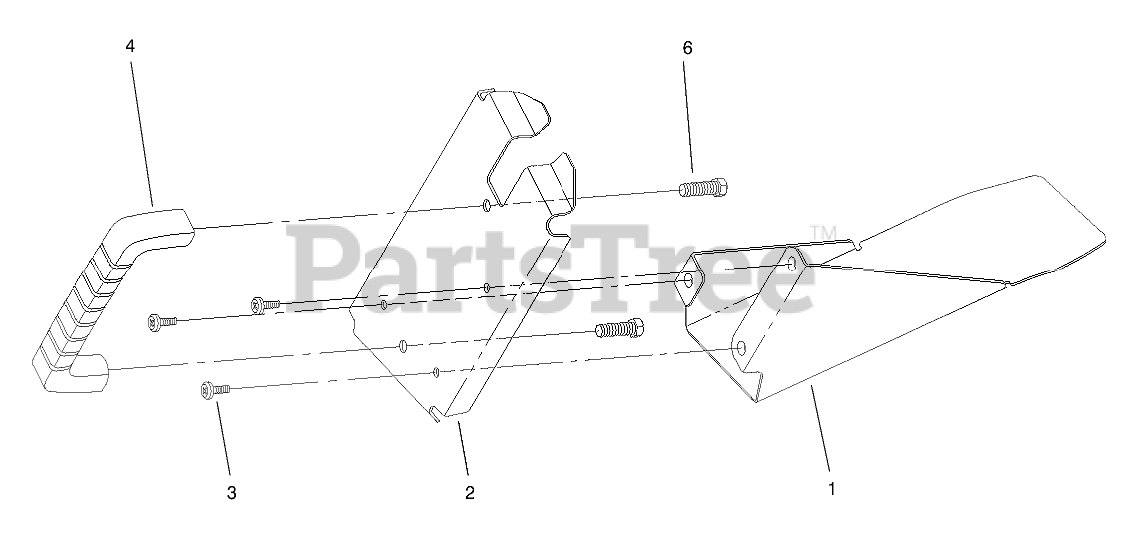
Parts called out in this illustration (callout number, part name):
1	SHIELD - DISCHARGE PLUG
2	COVER - DISCHARGE PLUG
4	HANDLE-DOOR
6	SCREW-HWH
